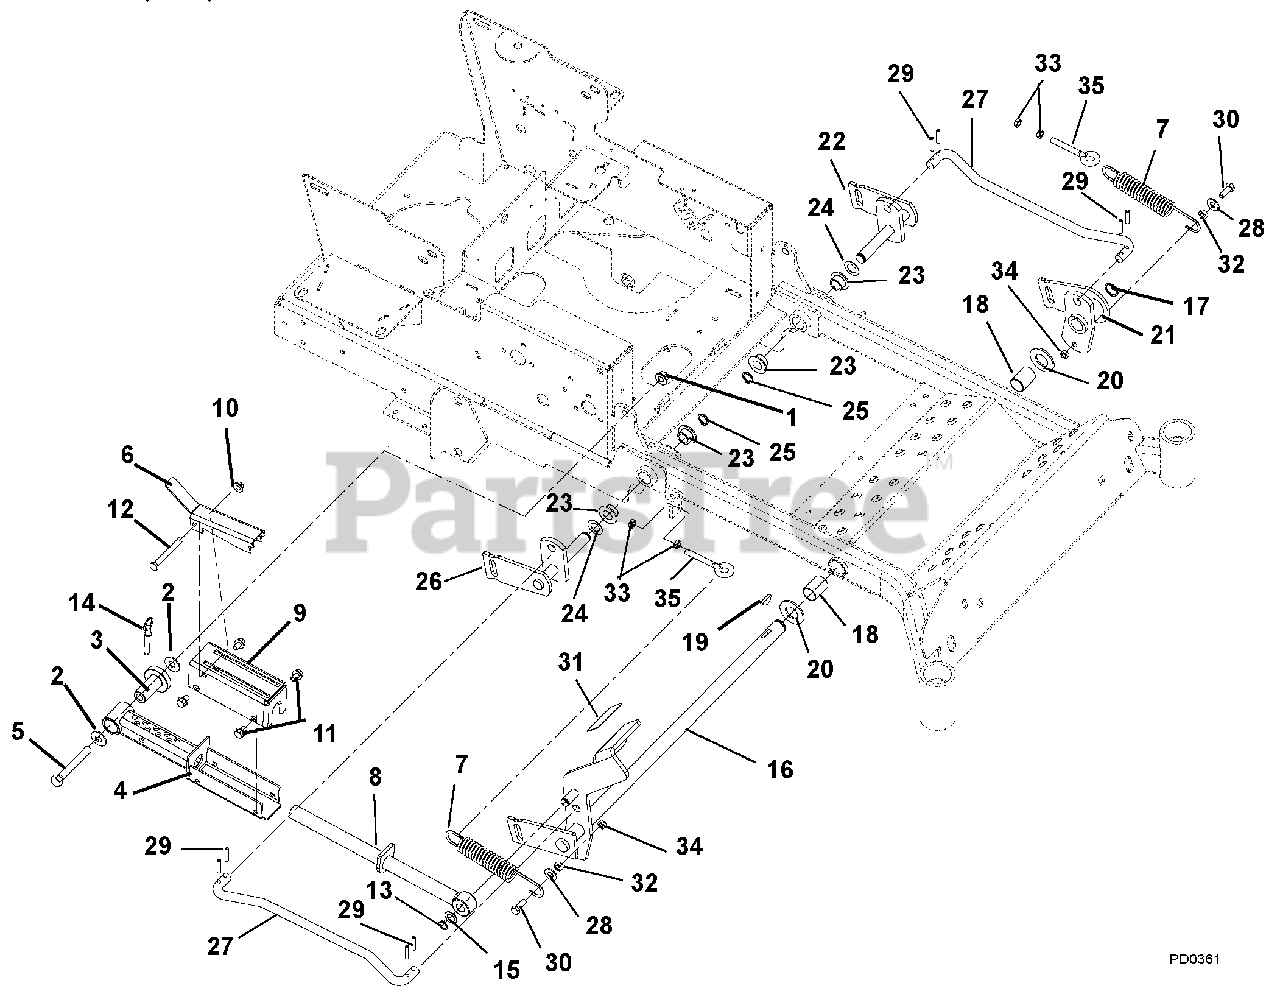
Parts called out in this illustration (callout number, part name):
1	@NUT-LK-NYL-FLG .50-13 YWZC
2	WSHR-FL-STL .531X1.250X.10 YWZ
3	BEARING, PEDESTAL
4	WMT, MECHANICAL LIFT
5	@BLT-HEX .50-13X3.75 GR5 YWZC
6	LOCK-UP, MECH LIFT
7	SG-TENS .162X1.25X8.25 WLD 25
8	WMT, MECH. LIFT SHAFT (.62)
9	WMT, MECH LIFT COVER
10	@NUT-LK-NYL-FLG .38-16 YWZC
11	@SCR-TAP .38-16X.50 HWH TR YWZ
12	@BLT-HEX .38-16X3.25 GR5 YWZC
13	RG-RTNG-EXT .625X.050
14	PIN, SPRING BALL .375OD X 1.50
15	WSHR-FL-STL .630X1.005X.062 YZ
16	WMT, FOOT OPERATED DECK LIFT
17	RG-RTNG-EXT 1.00X.078
18	BSHG,1.00ID X 1.125OD X 1.50LG
19	KEY-WDRF .25X1.00 HRD #15
20	WSHR-FL-STL- 1.062X2.0X.134 YZ
21	WMT, LH FRONT MOWER LIFT
22	WMT, LH REAR LIFT ARM (100)
23	BSHG-FLG .762X1.0X.580X1.48 NY
24	WSHR-HDND-THRST .758X1.23X.031
25	RG-RTNG-EXT .689X.078
26	WMT, RH REAR LIFT ARM (100)
27	ROD-LIFT ASSIST 16.35"
28	@WSHR-FL-STL.438X1.00X.083 YWZ
29	PIN-ROLL .250X1.25 STNLESS STL
30	@BLT-HEX .38-16X1.00 GR5 YWZC
31	GRIP, PEDAL 1.50 X 3.00
32	BSHG-SLV .377X.624X.235
33	NUT-HEX-JAM .375-16 YWZC
34	@NUT-LK-CTR-JAM .375-16 YWZC
35	BLT-EYE .375-16X2.50 YWZC
